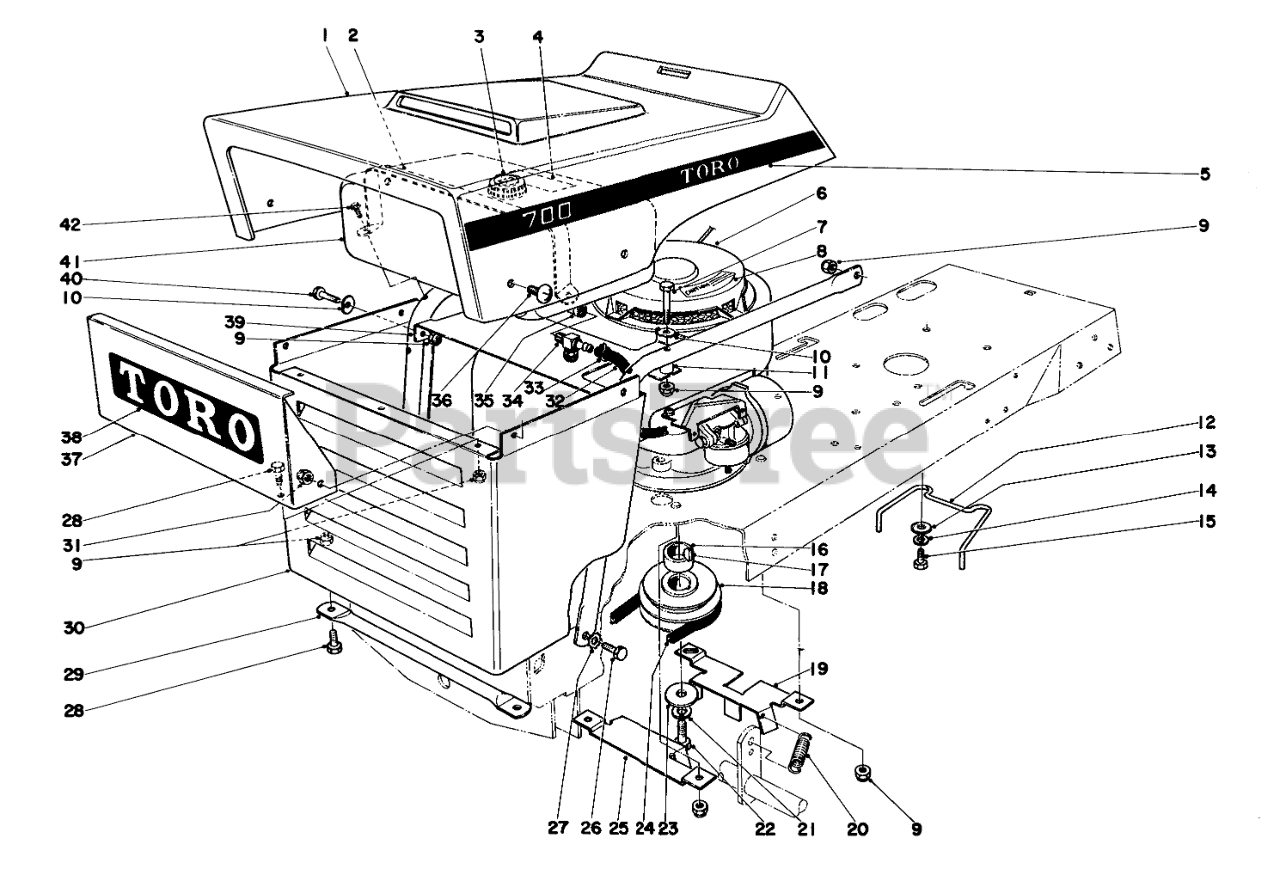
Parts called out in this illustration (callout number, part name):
2	Gas Tank Strap
3	GAS CAP
4	Decal
5	Decal-Hood, Left (Model 57131)
6	Engine (Model 57131)
7	SCREW-HH
8	Decal, Engine Shroud (Model 57017)
9	NUT-LOCK, CONE
10	WASHER
11	Spacer
12	Belt Retainer
13	WASHER-FLAT
14	WASHER-LOCK/SP
15	SCREW-HH
16	Spacer
17	KEY-WOODRUFF
18	Engine Pulley
19	Belt Guide
20	Spring Tension
21	WASHER-LOCK
22	SCREW-HH
23	Washer
24	ENGINE BELT
25	Belt Guide
26	SCREW-HH
27	WASHER-LOCK
28	SCREW-HH
29	Rod Grille Mount
30	Grille
31	NUT-LOCK, CONE
33	Clamp
34	Shut Off Valve
35	Elbow
36	Round Head Screw
37	Panel Grille
38	Decal-Grille Panel
39	Tray Gas Tank
40	SCREW-HH
41	GAS TANK
42	Screw
